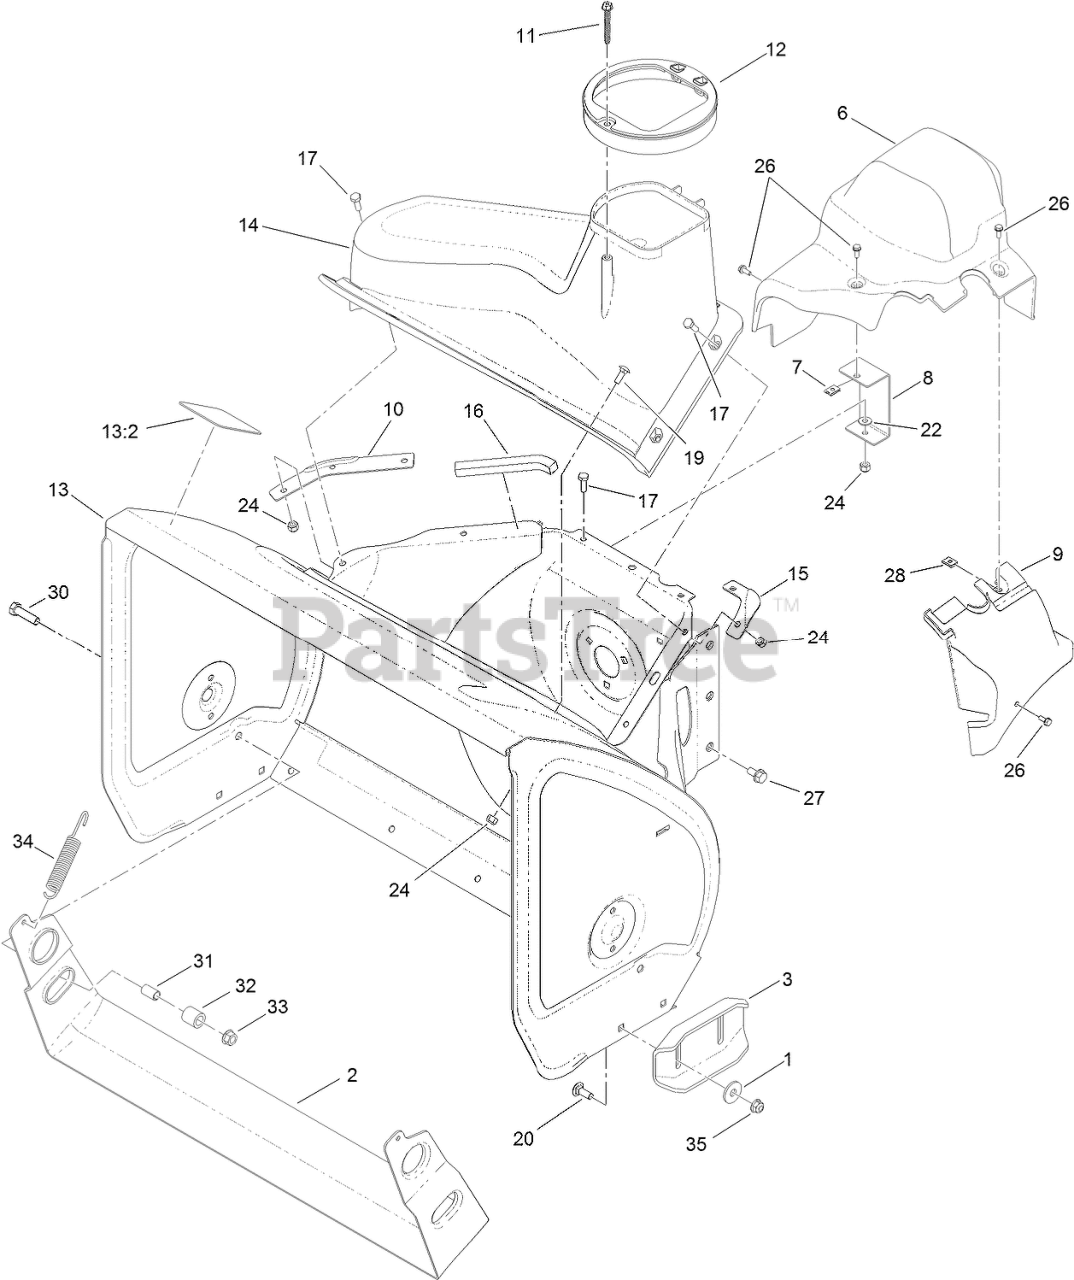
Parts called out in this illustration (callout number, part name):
1	WASHER
2	SCRAPER-PIVOTING, 28 INCH
3	SKID-CAST
6	COVER-BELT
7	NUT-SPEED, U-TYPE
8	BRACKET-COVER, CLIP NUT
9	COVER-EXTENSION, BELT
10	SEAL-FLANGE, COVER
11	SCREW-HWH, PLASTITE
12	GUIDE-CHUTE
13	HOUSING-AUGER, 28 INCH
13:2	DECAL-DANGER, AUGER
16	SEAL-HOUSING
17	SCREW-HH
19	BOLT-CARR
20	SCREW-CARR
22	WASHER-FLAT
24	NUT-LOCK, NI
26	SCREW-HWH
27	SCREW-HWHTF
28	NUT-SPEED
30	SCREW-HH
31	SPACER-SCRAPER, STOP
32	CUSHION-SCRAPER, STOP
33	NUT-HF
34	SPRING-SCRAPER
35	NUT-HF, NI
